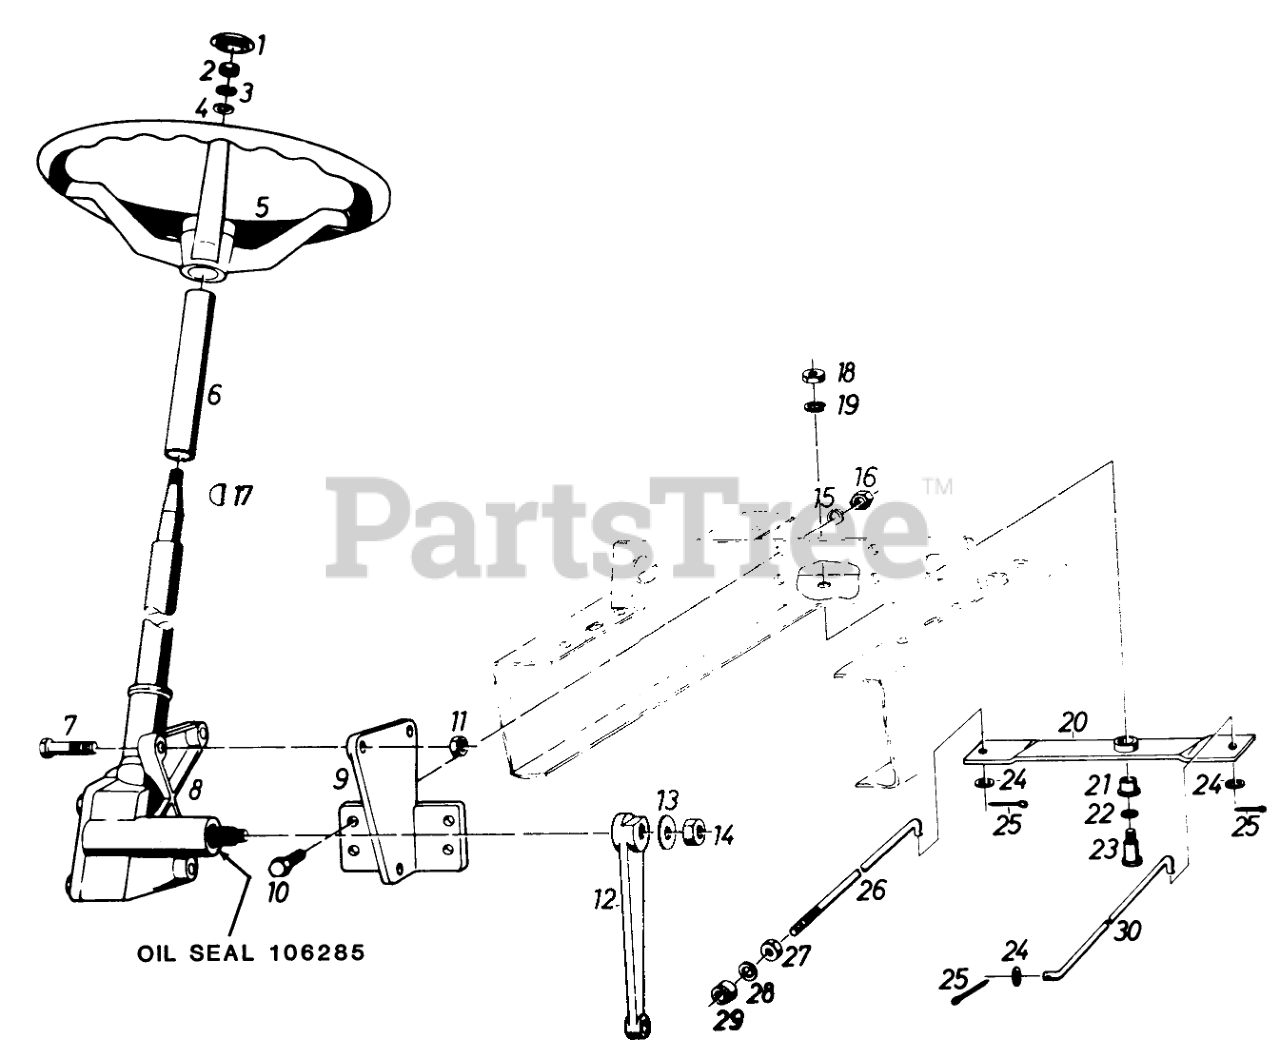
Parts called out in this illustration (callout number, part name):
1	Cover Cap
3	Lockwasher
4	Washer
5	Steering Wheel
7	Screw
8	Cam-Gears-Steering
9	Steering Bearing
10	Screw
12	Steering Arm
13	Lock Washer
15	Washer
19	Lockwasher
20	Lever Cpl. (Consisting of Parts 20 and 21)
21	Bearing
22	Washer
24	Washer
25	Split Pin
28	Washer
